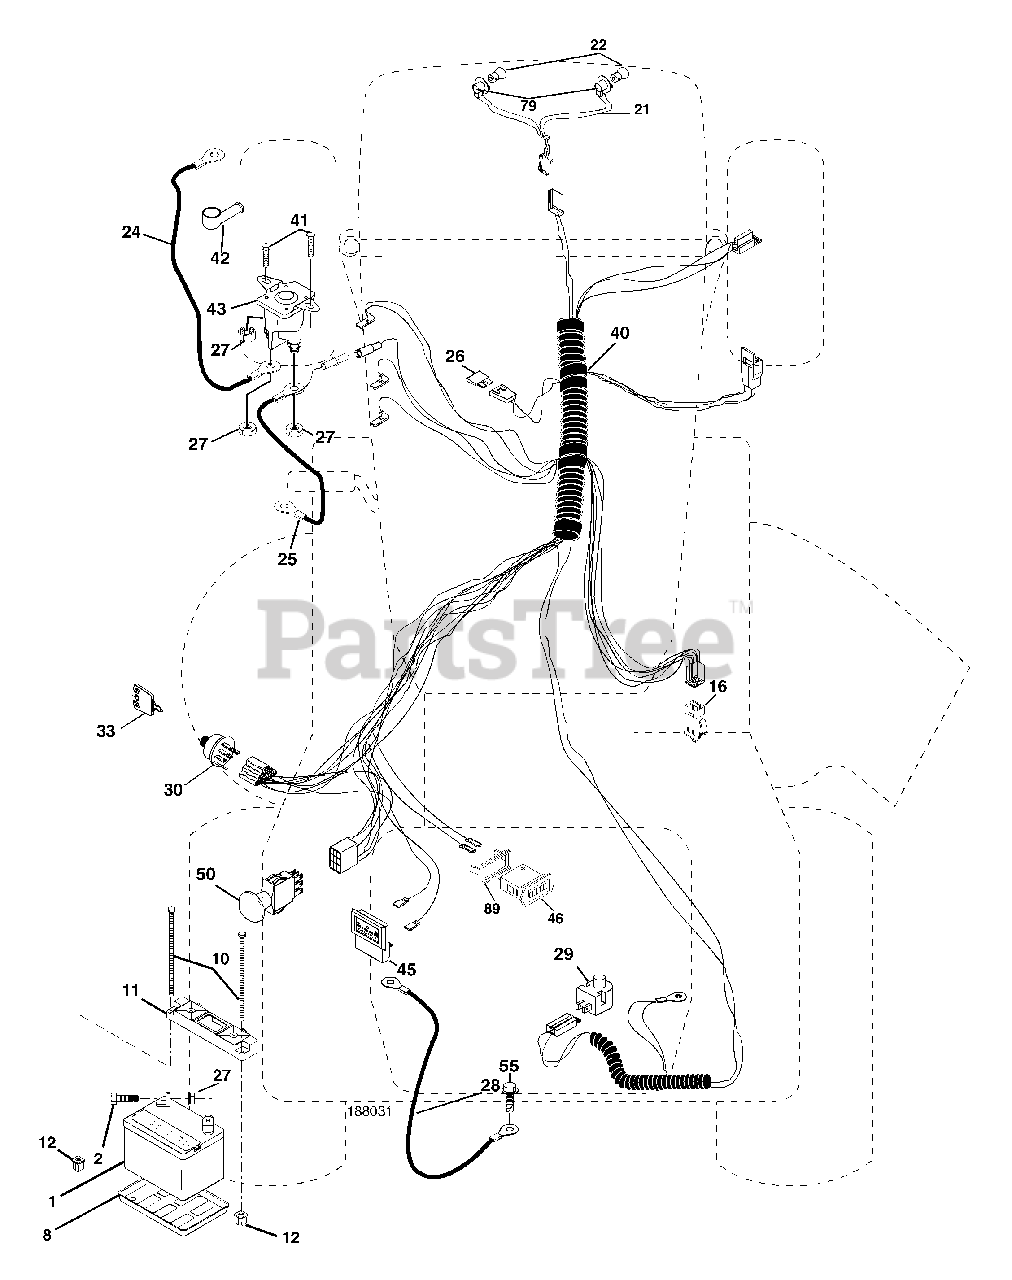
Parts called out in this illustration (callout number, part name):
1	Battery
2	Bolt Hex Hd 1/4-20 unc x 3/4
8	Tray, Battery
10	Bolt, BTR FRT 1/4-20 x 7.5
11	Hold Down Battery, Front
12	Nut, Push, Nylon
16	Switch Interlock Push-In
21	Harness Asm Light W/Bulbs
22	Bulb Light
24	Cable Battery
25	Cable Batterywire
26	Fuse
27	Nut Keps Hex 1/4-20 unc
28	Cable Ground
29	Switch Plunger Normal NC Gray
30	Switch Ign 4 pos w/lights
33	Key Ign
40	Harness Ign.
41	Bolt Blk Fin Hex 1/4-20 x 1/2
42	Cover Terminal Red
43	Solenoid
45	Ammeter Rectangular
46	Hourmeter Snap-In
50	Switch, PTO
55	Screw Thdrol 5/16-18 x 1/2
79	Bulbholder
89	Bracket Snap-In Hourmeter
